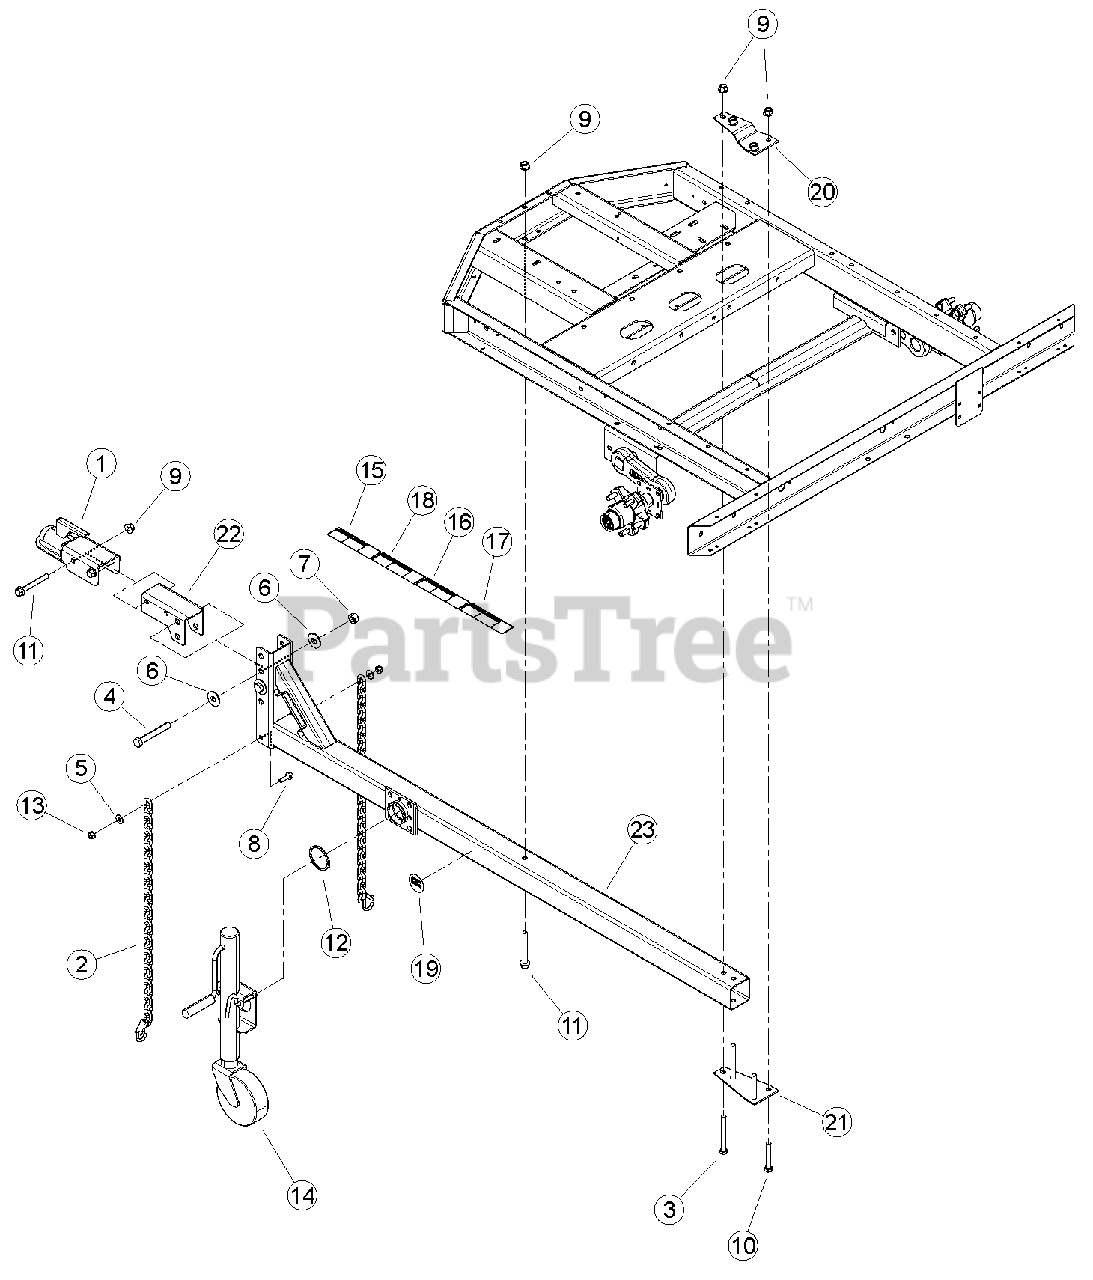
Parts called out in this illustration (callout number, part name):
1	COUPLER, 2 IN
2	CHAIN, SAFETY 5000 LB W/LATCH
3	BOLT, 1/2 X 4-1/2" GR5 HHCS NC ZP
4	BOLT, 5/8 X 4-1/2 HEX HD G5 ZP
5	WASHER, 3/8" FLAT ZP
6	WASHER, 5/8" FLAT ZP
7	NUT, 5/8" CENTERLOCK ZP GR5
8	BOLT, 3/8 X 1-1/4 FLANGE NC
9	NUT, 1/2-13 NYLOCK FLANGE
10	BOLT, 1/2 X 3-1/4" GR5 HHCS NC ZP
11	BOLT, 1/2-13 X 4 HWH GR5 CZP
12	SNAP RING, 2-1/2 EXTERNAL
13	NUT, 3/8-16 NYLOCK FLANGE
14	JACK, PIVOTING W/ SWIVEL CASTOR
15	DECAL, SAFETY CHAINS
16	DECAL, TRAILER ELECTRICAL
17	DECAL, CHECK WHEELS
18	DECAL, SAFE COUPLING
19	DECAL, NATM COMPLIANCE
20	PLATE, AXLE SAFETY
21	PLATE, AXLE SAFETY
22	MOUNT, COUPLER
23	WELDMENT, HITCH POLE
